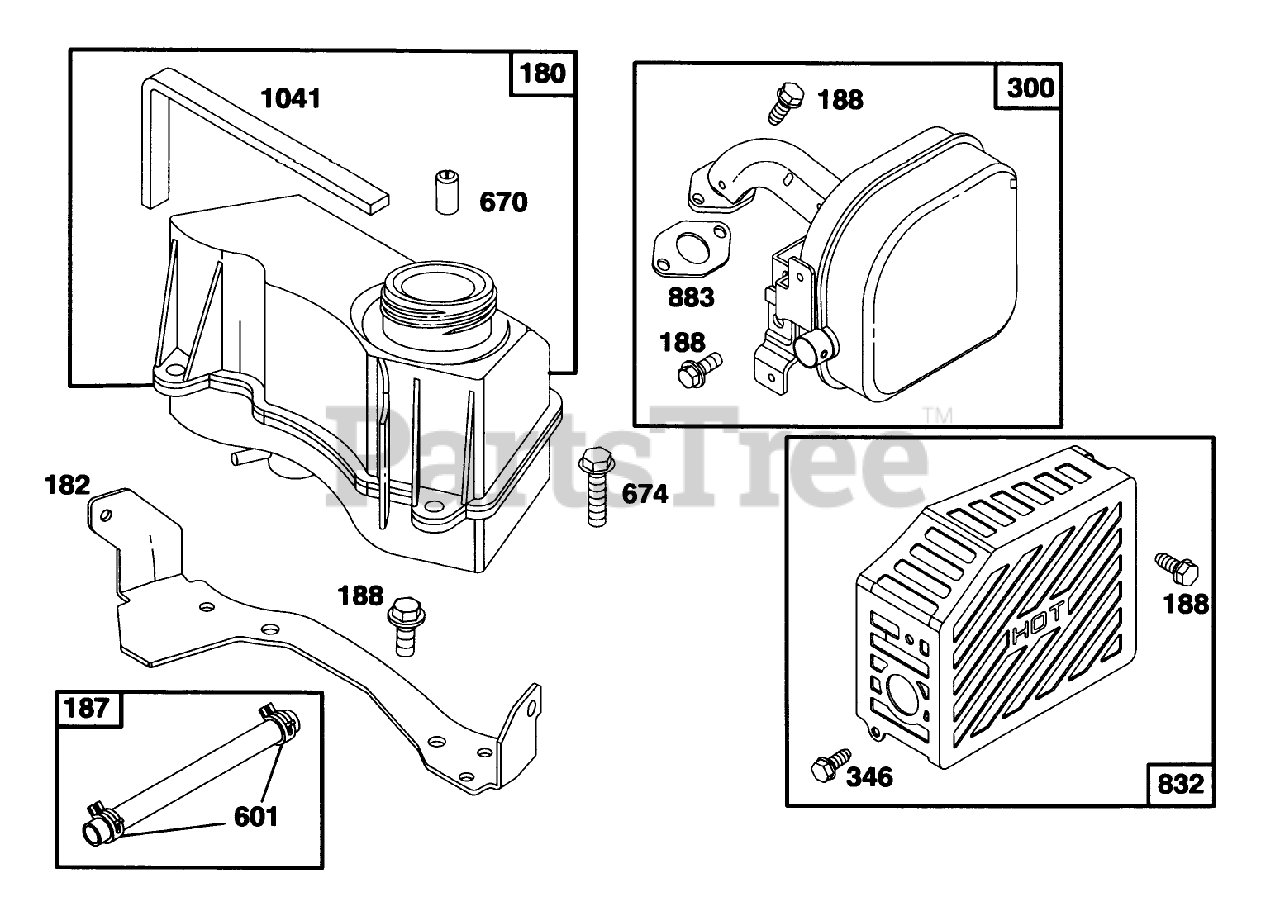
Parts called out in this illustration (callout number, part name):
180	TANK ASSY - FUEL
187	BRIGGS 296004
300	MUFFLER - EXHAUST
670	SPACER
674	SCREW - HEX HEAD
